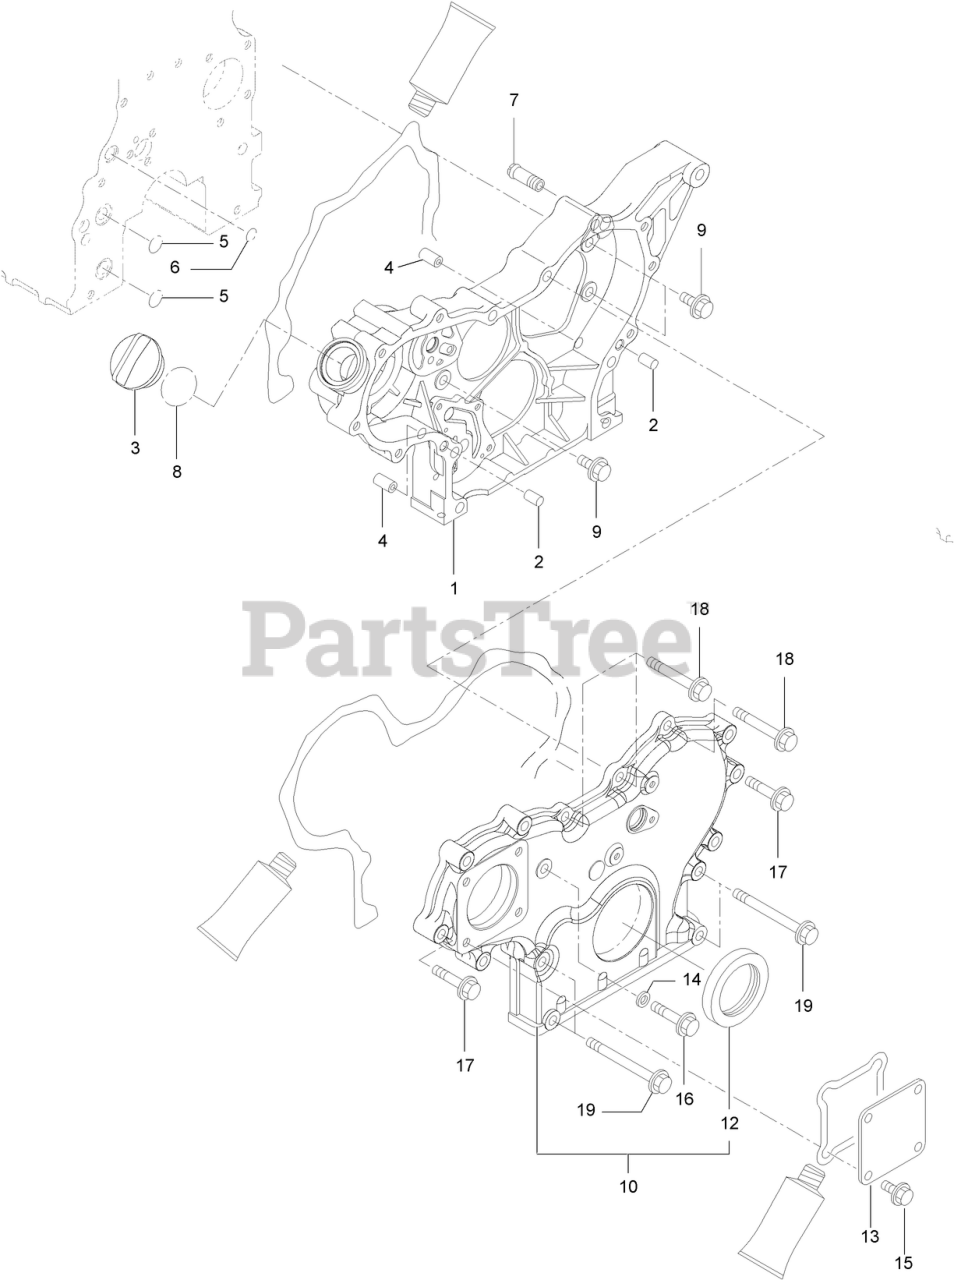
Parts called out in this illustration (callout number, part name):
1	CASE-GEAR
3	COVER-FILLER
5	O-RING
6	O-RING
8	O-RING
10	GEARCASE COVER ASM
12	SEAL-OIL
14	WASHER-SEAL
